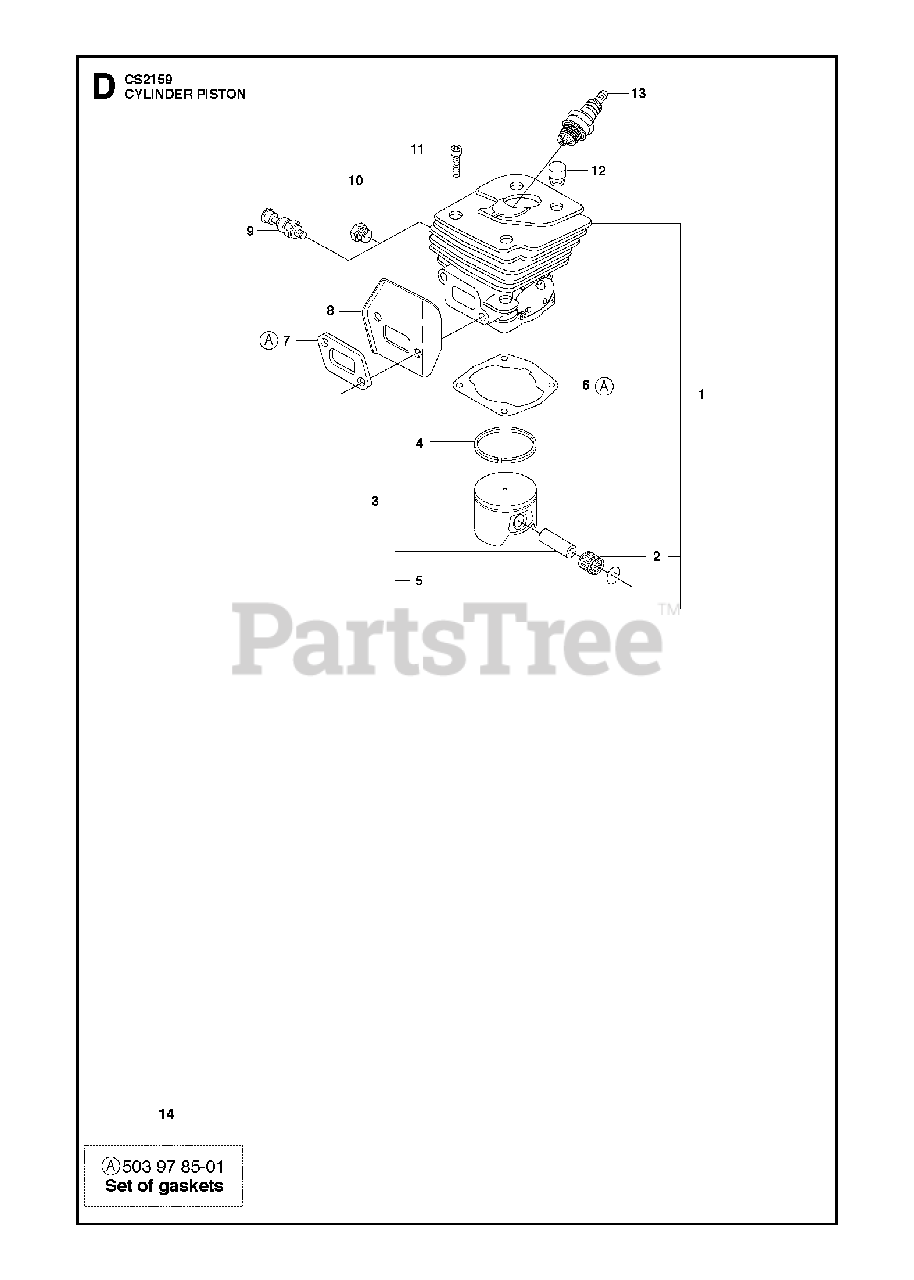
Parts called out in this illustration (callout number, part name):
2	SUPPORT BUSHING
3	PISTON
4	%PISTON RING
6	GASKET
7	GASKET
8	HEAT DEFLECTOR
9	DECOMPRESSION VALVE
10	CYLINDER PLUG
11	SCREW MC6S 5X25
13	SPARK PLUG RCJ7Y
14	GASKET SET
